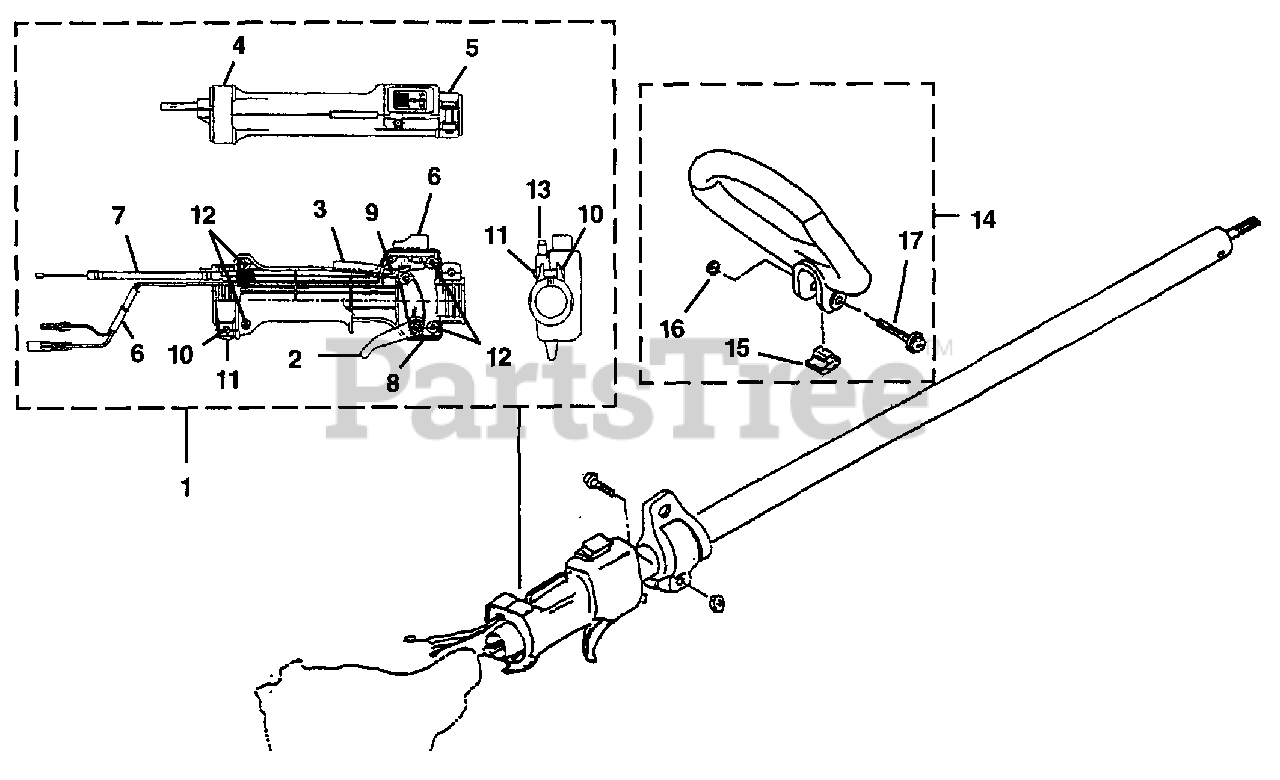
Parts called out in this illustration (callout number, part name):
1	CONTROL LEVER ASSEMBLY
2	THROTTLE-Trigger
3	LATCH-Trigger
6	WIRE AND CABLE SET
7	THROTTLE CABLE
12	SCREW-Tapping
13	LOCK-Throttle Start
14	HANDLE ASSEMBLY
16	NUT-Flange (M6)
17	BOLT-Cross Recess
